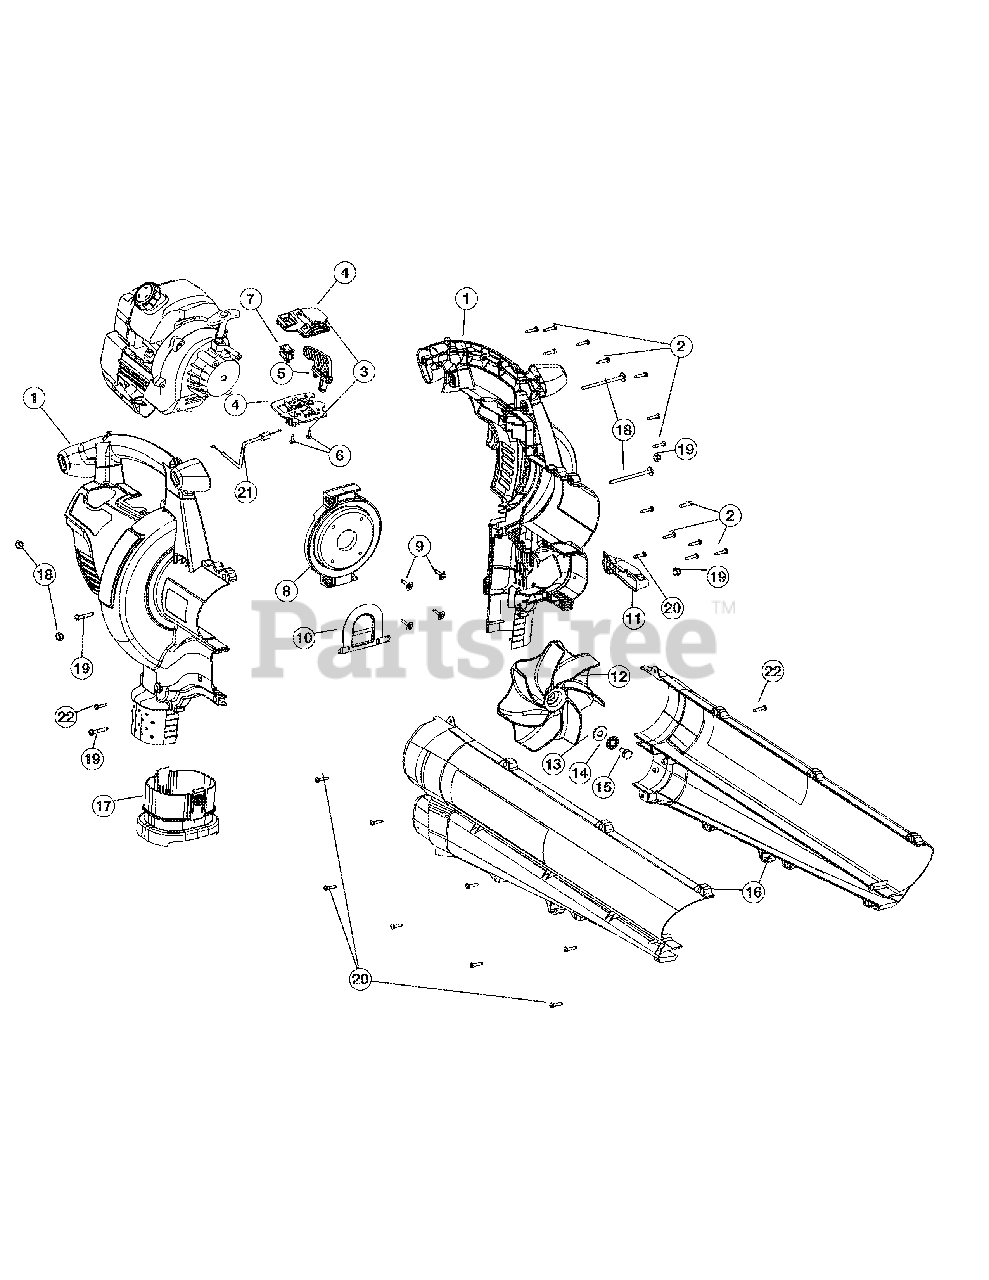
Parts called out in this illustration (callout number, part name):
1	Engine Cover Assembly
2	Cover Screw
3	Throttle Control Assembly
4	Throttle Control Plates
5	Throttle Control Lever
6	Screw, Plastic
7	Rocker Switch Assembly
8	Engine Mounting Plate
10	Mode Control Flapper
11	Mode Control Lever
12	Impeller Blade
13	Washer
14	Lock Washer
16	Blower/Vac Tube Assembly
17	Vacumm Bag Adapter
18	Mounting Plate Hardware
19	Blower/Vac Tube Mounting Hardware
21	Throttle Cable
